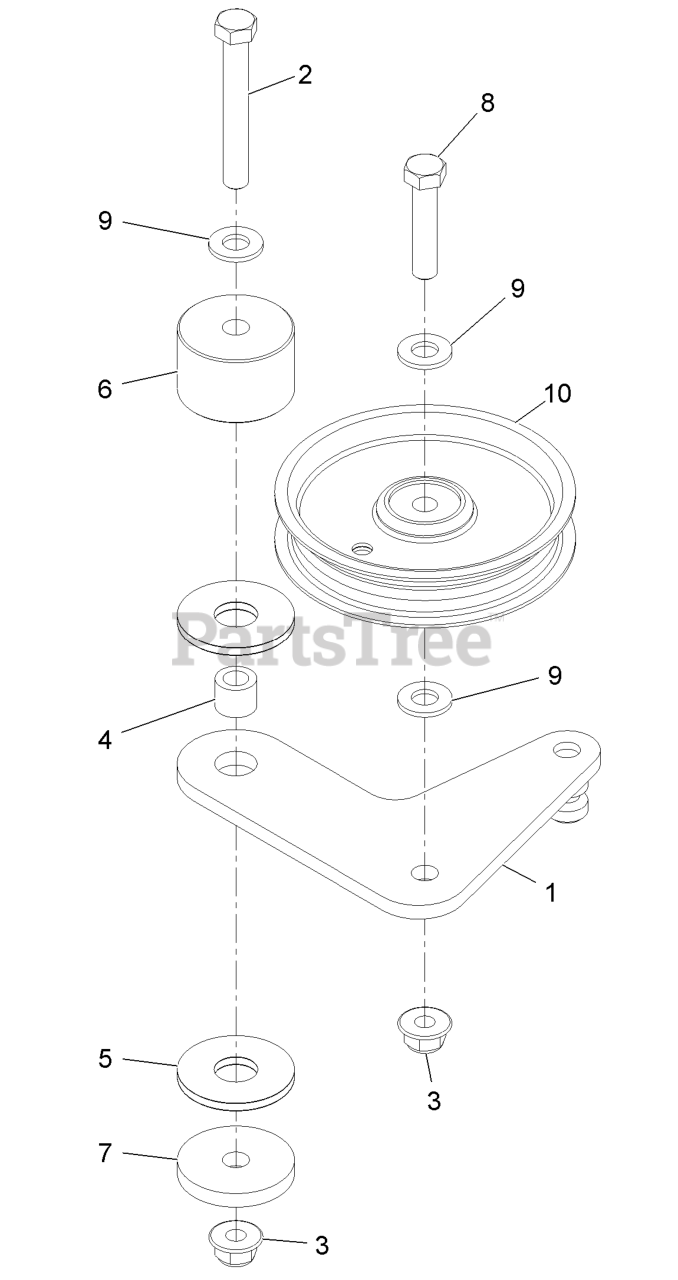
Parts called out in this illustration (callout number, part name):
1	PLATE-IDLER
2	SCREW-HH
3	NUT-HF, NI
4	BUSHING-LEVER, LIFT
5	WASHER-FRICTION, COMPOSIT
6	HUB-IDLER
7	WASHER-PLAIN
8	SCREW-HH
9	WASHER-FLAT
10	PULLEY-IDLER
